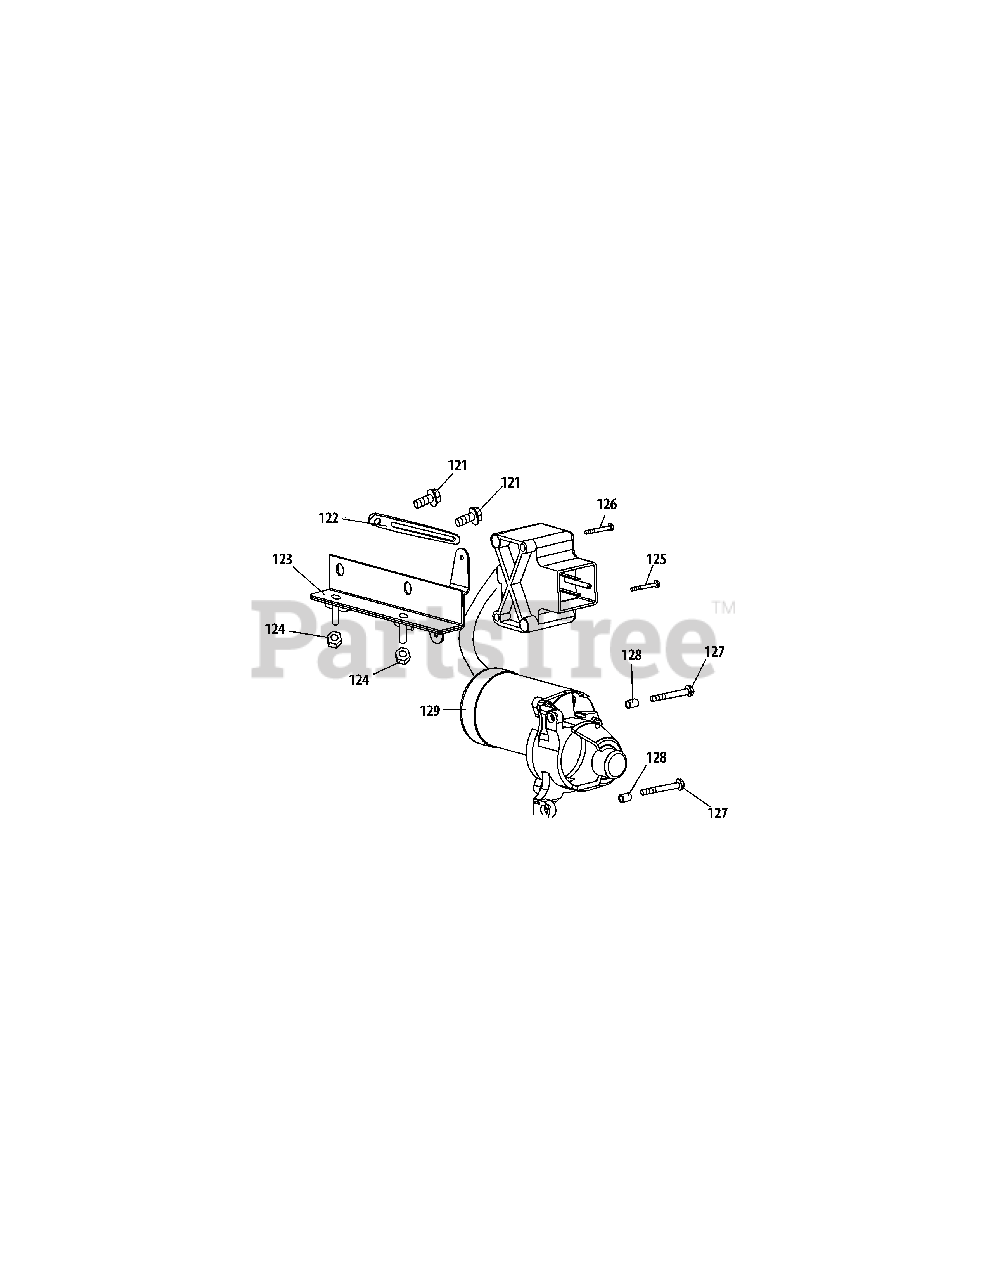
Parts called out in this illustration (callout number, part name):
121	Bolt M6×10
122	Wire Clip
123	Switch Housing Mounting Bracket
124	Nut, M6
125	Bolt M4×55
126	Bolt M4×60
127	Bolt M6×32
128	Dowel Pin 8×8
129	Electric Starter
